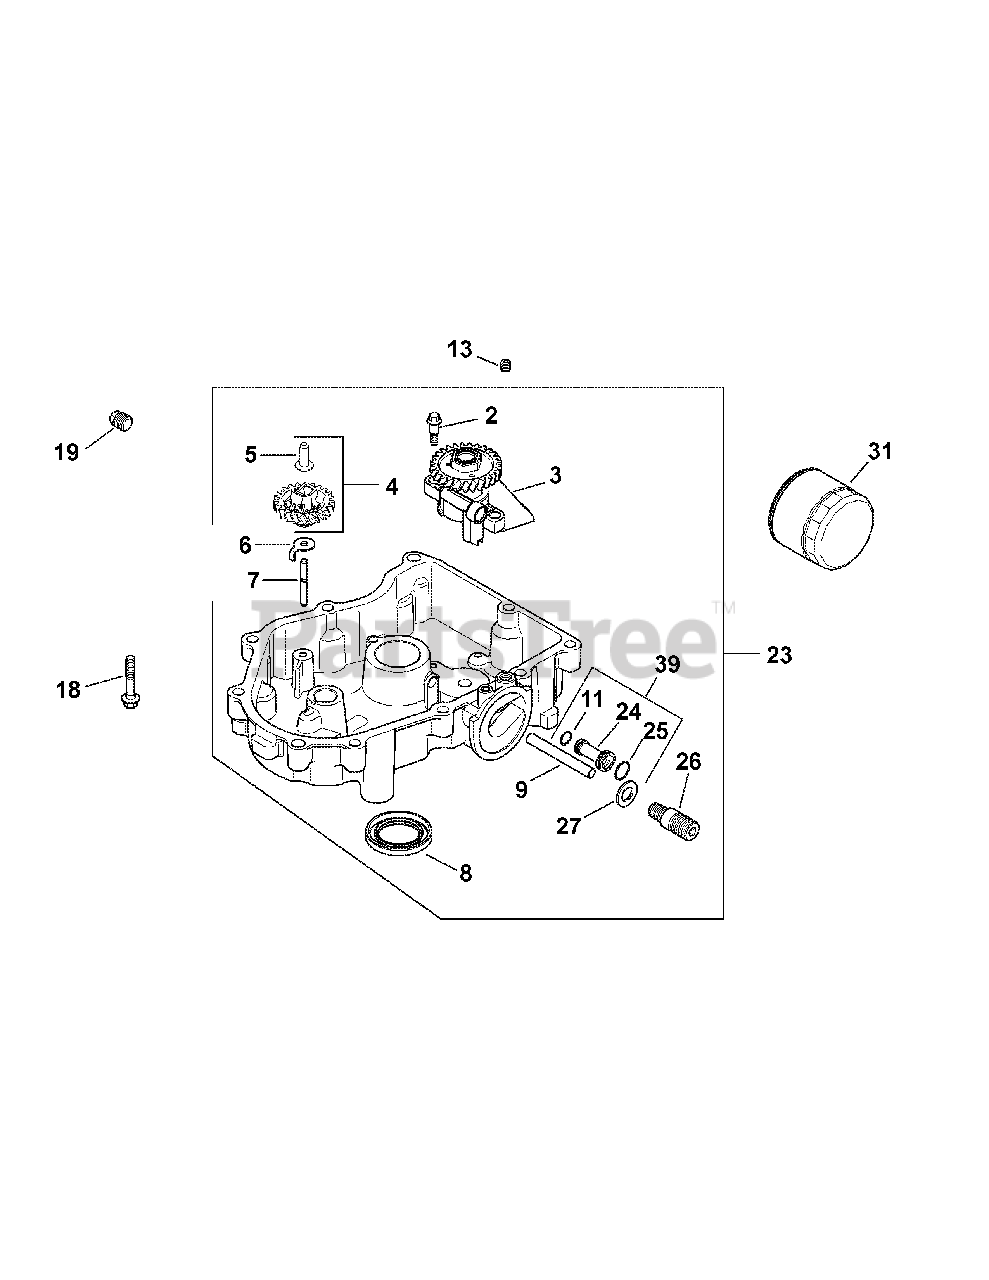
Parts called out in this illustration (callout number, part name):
2	Shd. Thd. Frm. Screw, M6 X .0 X 6.5
3	Oil Pump Assembly
4	Governor Gear w/ Pin Kit
5	Governor Regulating Pin
7	Governor Gear Shaft
9	Oil Feed Tube - Filter To Pan
11	Oil Pick-Up O-Ring
13	Plug, Ctsk. Pipe Plug, 1/8
18	Flg. Screw, M8 x 1.25 x 45
19	Sq. Hd. Pipe Plug, 3/8
23	Oil Pan Assembly
24	Oil Feed Tube
26	Oil Filter Nipple
39	Oil Feed Tube Assembly
